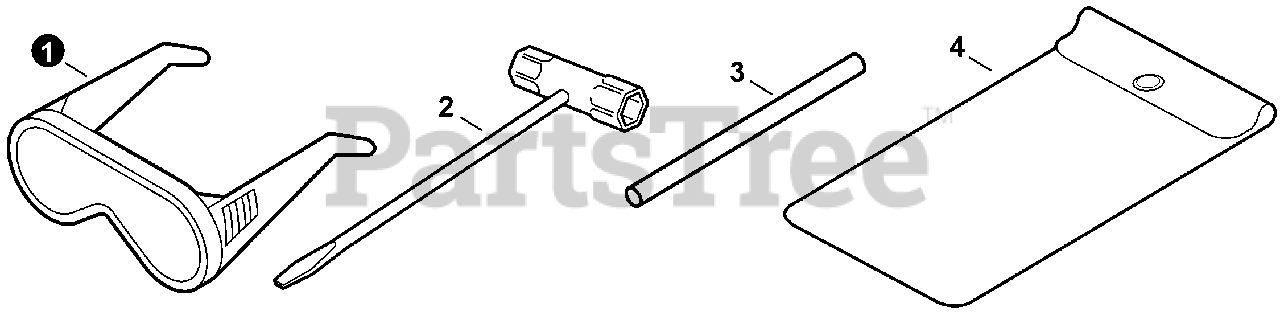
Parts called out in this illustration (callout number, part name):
1	GLASSES, SAFETY
2	T-WRENCH 17x-19 L200
3	TOOL, LOCKING 5×120 MM
4	BAG, TOOL
